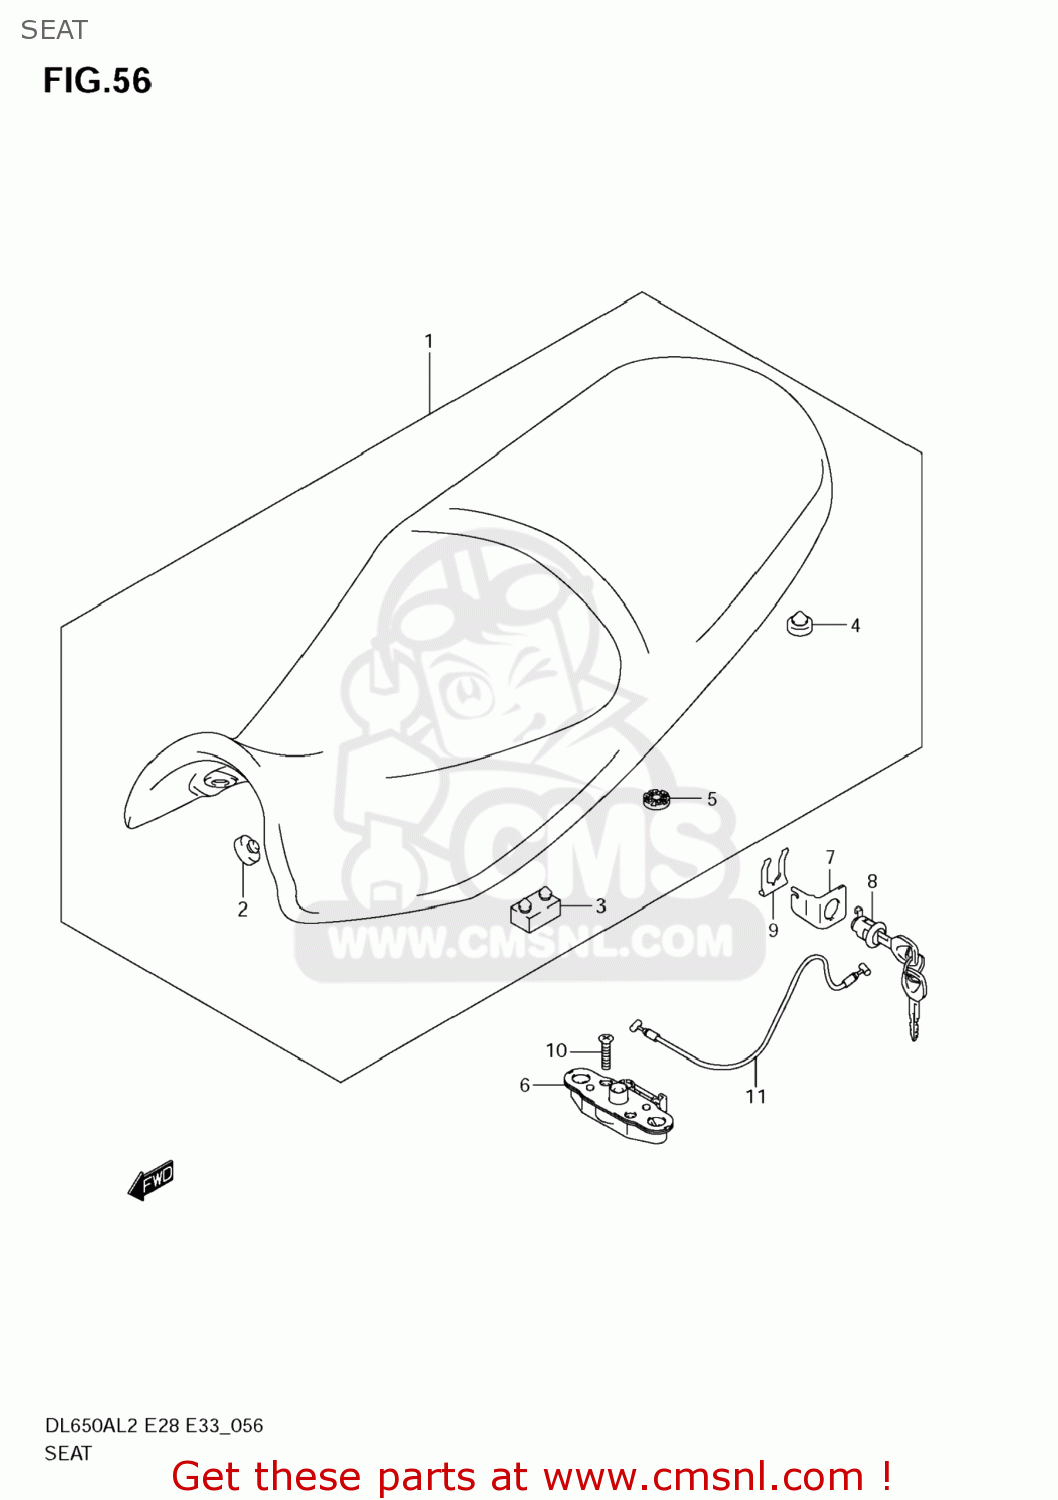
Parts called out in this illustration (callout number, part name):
1	SEAT ASSY
2	CUSHION,SEAT
3	CUSHION,SEAT(40X20X15)
4	CUSHION
5	CUSHION,SEAT LOCK(10X22X6)
6	BRACKET,SEAT SUPPORT
7	GUIDE,SEAT LOCK CABLE
8	LOCK SET,SEAT
9	PLATE,SEAT LOCK ASSY
10	SCREW
11	CABLE,SEAT LOCK
